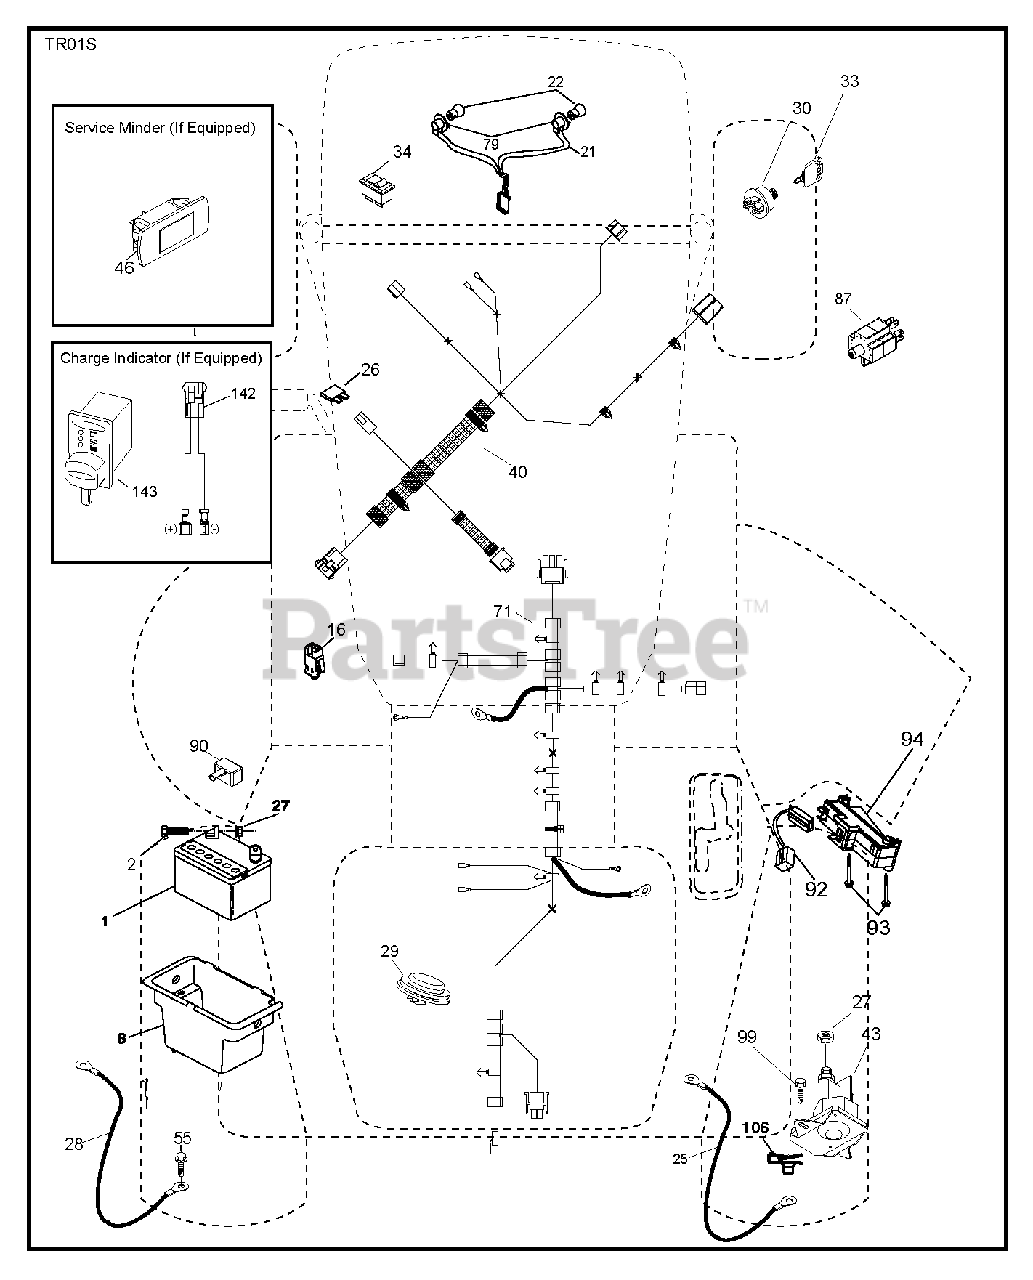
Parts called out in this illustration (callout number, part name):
1	Battery, Dry 30 Amp
2	BOLT.HEX.1/4.X.3/4.DICHROMATE
8	BOX.BATTERY.MNT.REAR.L
16	SWITCH INTERLOOK PUSH-IN
21	HARNESS.LIGHT W/4152J BULBS
25	CABLE.BATT.RED.8GA.17
26	FUSE 20AMP
27	NUT
28	CABLE.GROUND.REAR.BATTERY.8G
29	SWITCH.SEAT.DELTA.OPC.
30	SWITCH.IGN.DELTA.W.LGH.ROS
33	KEY.CHAIN.BLISTER.PACK.GEN.USA
40	HARNESS.CHASSIS.RRBATT.RDYSTRT
43	SOLENOID.STARTER.BRASS.PLUNGER
55	SCREW 5/16"
71	HARNESS.TEX.CHSSIS.REAR.BATT
79	BULB HOLDER ASM.
87	SWITCH.INTRLCK.CLUTCH.
90	COVER.TERMINAL.BATTERY
92	HARNESS.PIGTAIL.CONSLE
93	SCREW.PLASTITE
94	MODULE.REVERSE.ROS
99	SCREW HEXWSHR 1/4-20X3/4
106	1/4-20 U NUT
